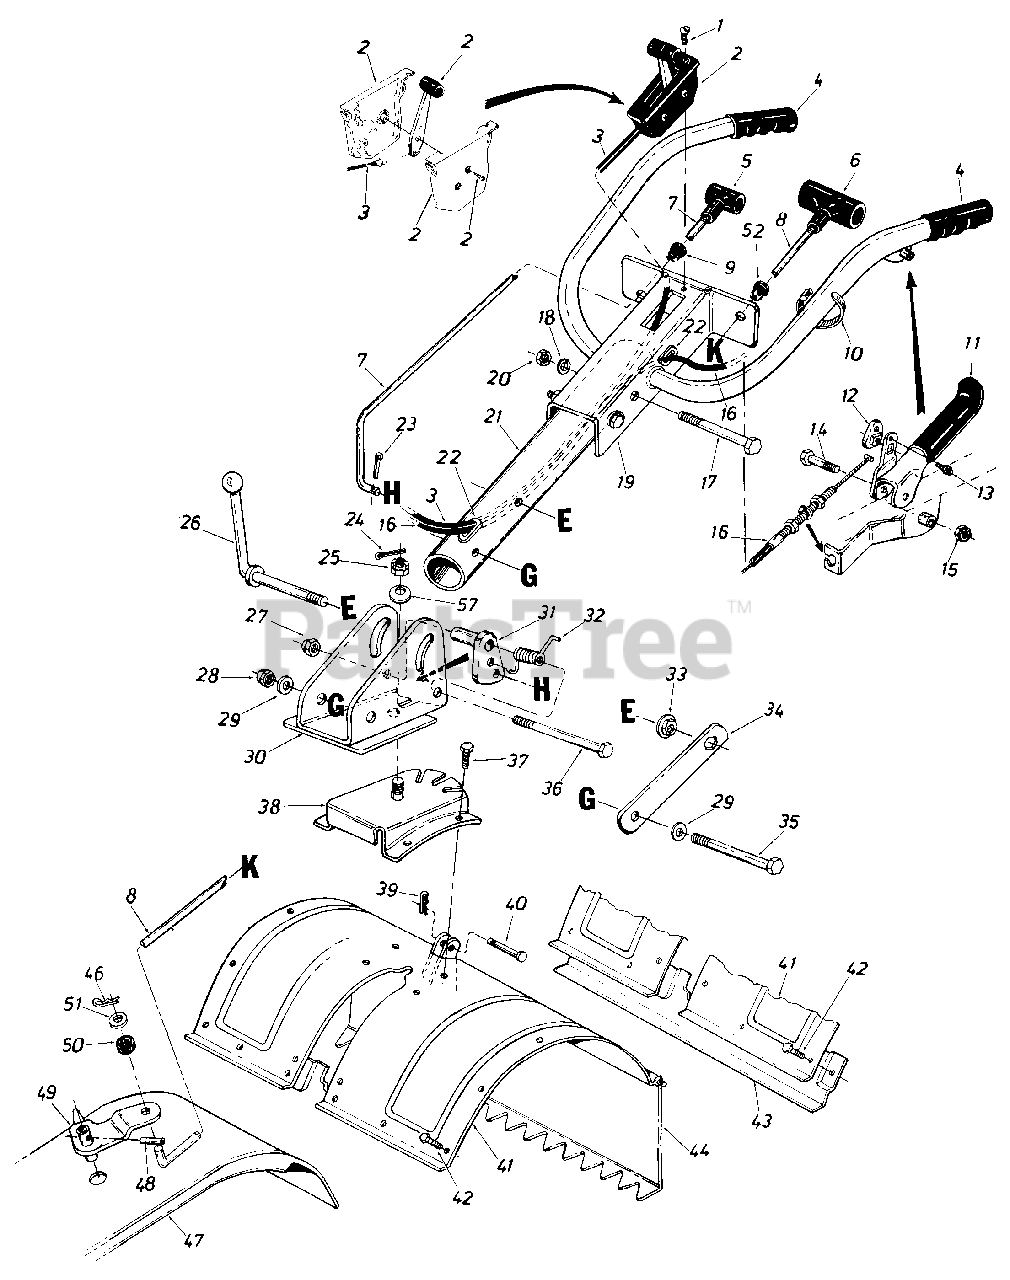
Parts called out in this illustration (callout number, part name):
1	Truss Mach. AB-Tap. Scr. #10 x .50" Lg.
2	Throttle Control Box Ass'y.
3	Throttle Control Wire
4	Handle Grip
5	Small "T" Knob
6	Large "T" Knob
8	Control Rod .33 Dia. x 37" Lg.
9	Snap On Bushing 3/8" Dia.
10	Cable Tie-Self Clinching
11	Clutch Grip Ass'y.-L.H.
12	Barrel Cable Hold Down
13	Hex B-Tap Scr. #10 x .44" Lg.
14	Hex Bolt 3/8-16 x 2.0" Lg.*
15	Hex Cent. L-Nut 3/8-16 Thd.
16	Clutch Control Cable 53" Lg.
17	Hex Bolt 3/8-16 x 3.00" Lg.*
18	L-Wash. 3/8" I.D.-H.D.
23	Cotter Pin 3/32" Dia. x .75"-Lg.*
24	Cotter Pin 3/32" Dia. x 1.25" Lg. *
25	Hex Slotted Nut 5/8-18 Thd.
26	Handle Adj. Crank
27	Hex Cent. L-Nut 3/8-16 Thd.
28	Hex Nut 3/8-16 Thd.*
29	Bell-Wash. .400" I.D. x .87" O.D.
30	Handle Pivot Bracket
31	Positioner Crank Ass'y.
32	Spring Handle Adj.
33	Hex Flange Nut 3/8-24 Thd.
34	Bracket Hex Nut Retainer
35	Hex Bolt 3/8-16 x 3.25" Lg.*
36	Hex Bolt 3/8-16 x 3.00" Lg.-Gr. 8
37	Hex Bolt 3/8-16 x .75" Lg.*
38	Handle Positioner Brkt. Ass'y.
39	Intern. Cotter Pin
40	Clevis Pin .375" Dia.
43	Bracket Reinforcement- 0 18"
46	Intern. Cotter Pin 5/16" Dia.
48	Spring Roll Pin 3/16" Dia. x 1.00" Lg.
49	Shifting Crank Ass'y. D x 2.05
50	Rubber Washer .33" I.D. x .87" O.D.
51	Fl-Wash. .400" I.D. x 1.250" O.D.
52	Snap On Bushing 1/2" Dia.
57	Bell-Wash. .630" I.D. x 1.25" O.D.
14979-0638	SHIELD-REAR TINE - MTD/TROY-BILT RED (0638)
